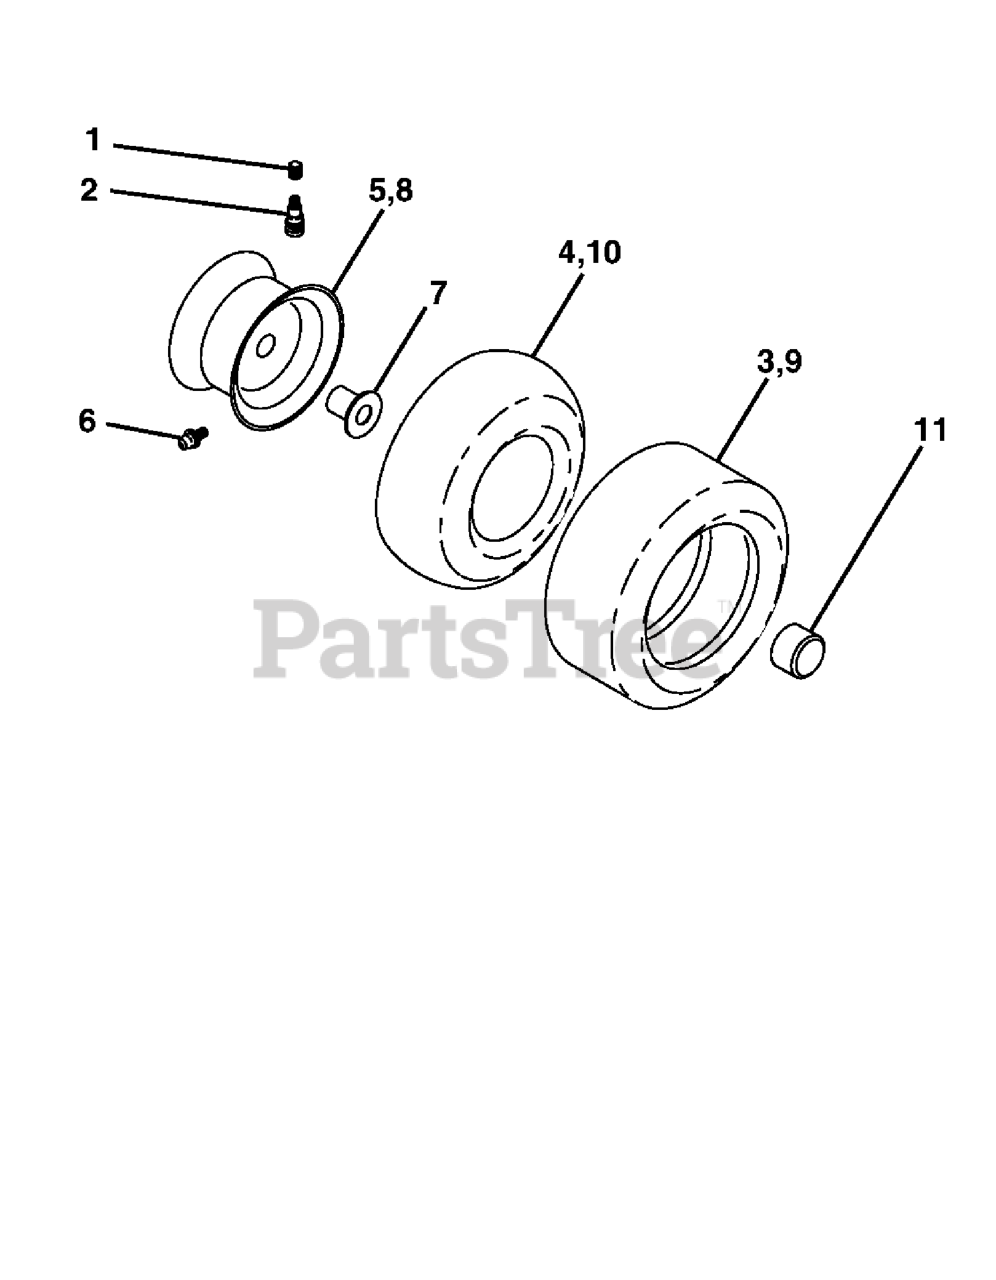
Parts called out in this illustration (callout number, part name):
1	VALVE CAP
2	VALVE STEM LT
3	TIRE HEAVY DUTY
4	TUBE.5.3/4.5/6
5	RIM ASM 6" FRONT SILVER
6	FITTING LT
7	BEARING T
8	RIM ASM 8" REAR SILVER
9	TIRE.20X8-8.TURF.SAVER
10	TUBE
11	CAP, AXLE BLK
